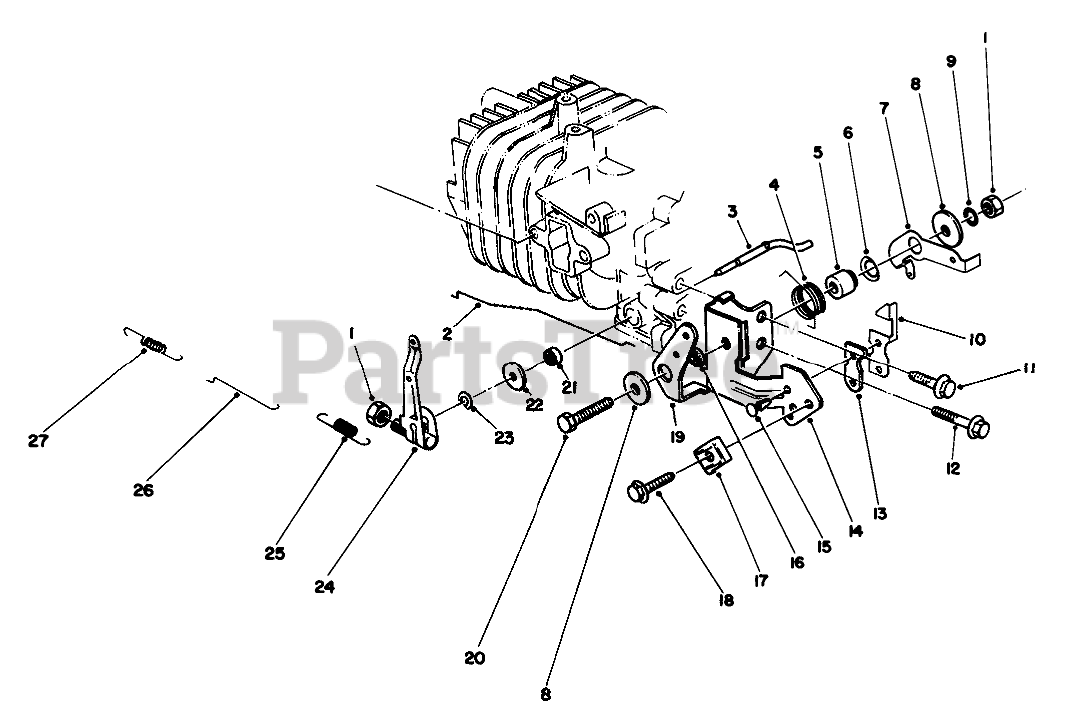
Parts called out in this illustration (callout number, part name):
2	CHOKE ROD
3	Shaft-Govemor
4	SPRING-CHOKE LEVER
5	Gov Lever Spacer
6	Washer-Gov. Spring Lever
7	LEVER-SPRING, GOVERNOR
8	WASHER
9	LOCKWASHER
10	TERMINAL-KILL SWITCH
13	INSULATOR-KILL SWITCH
14	BRACKET-THROTTLE, CONTROL
15	KILL SWITCH RIVET
16	SPACER-CHOKE LEVER
17	CLAMP
19	LEVER-CONTROL, CHOKE
21	SEAL-OIL
22	WASHER
23	E-RING
24	GOVERNOR ARM
25	SPRING-GOVERNOR
26	ROD-CARBURETOR
27	SPRING
